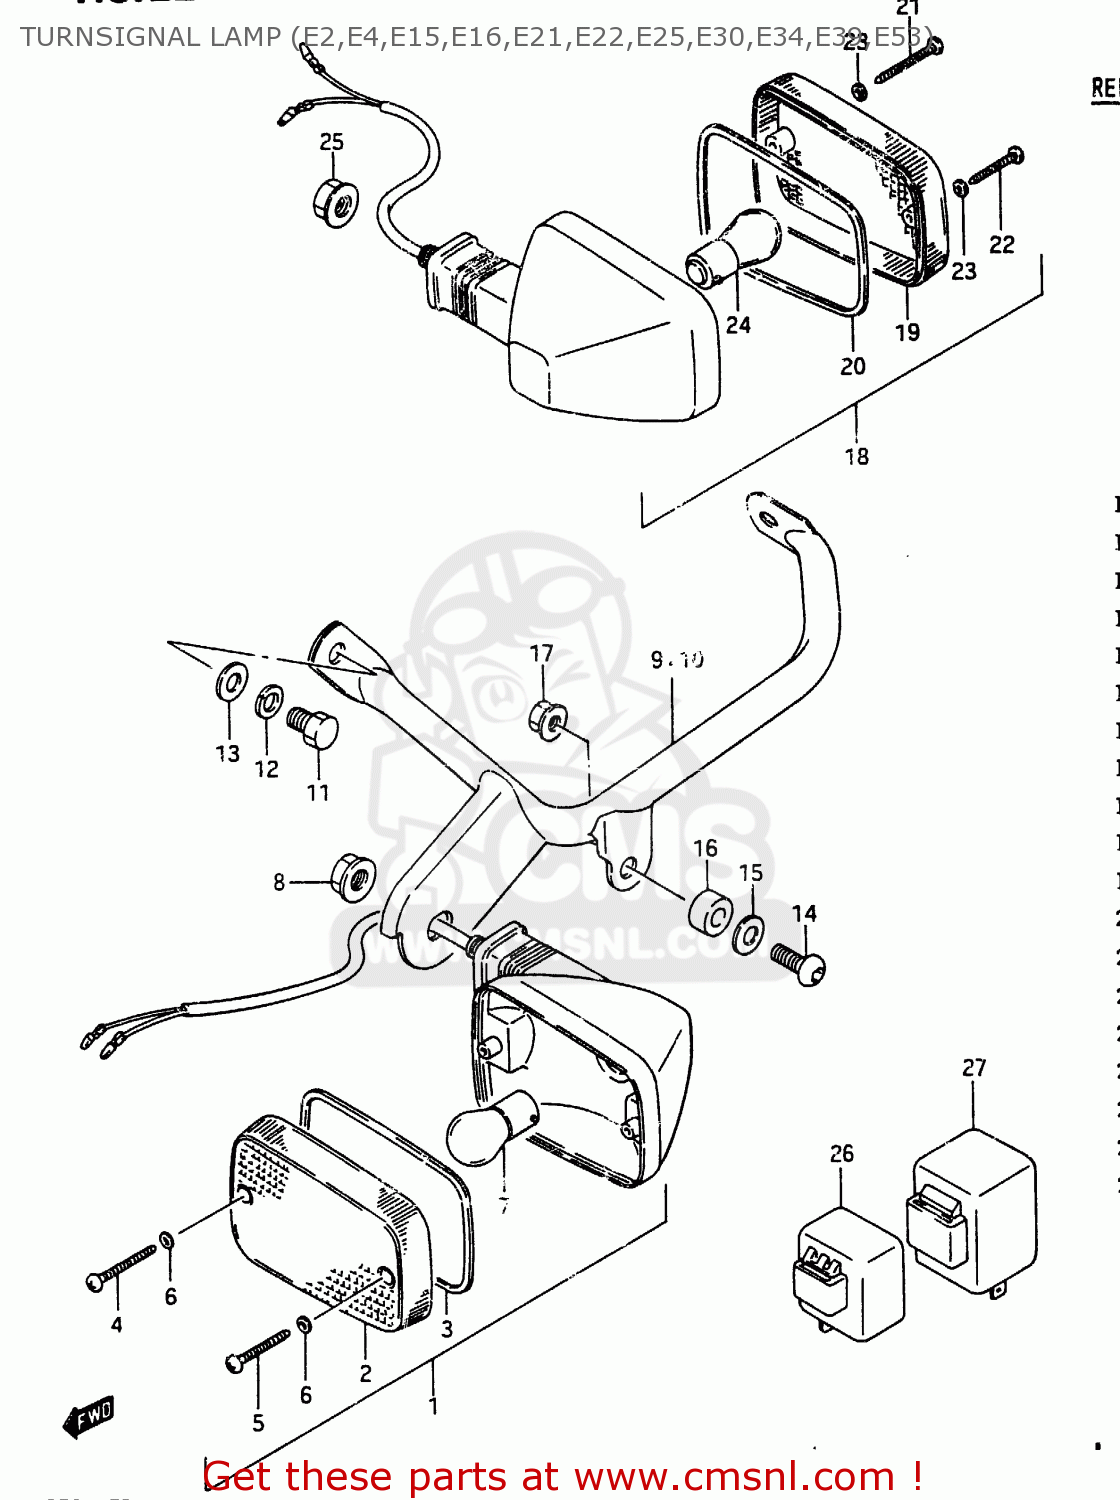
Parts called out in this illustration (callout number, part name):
1	LAMP ASSY,FR
2	LENS,FR
3	GASKET (NAS)
4	SCREW,TURN SIG LENS FITTING
5	SCREW
6	GASKET (NAS)
7	BULB(12V21W)
8	NUT
9	BRACKET, FRONT TURNSIGNAL RH
10	BRACKET,FR TURNSIGNAL,L
11	BOLT
12	WASHER,LOCK,8.
13	WASHER
14	SCREW(6X30)
15	WASHER(6.5X16X1.2)
16	SPACER(6.1X8X14.5)
17	NUT
18	LAMP ASSY,RR
19	LENS,RR
20	GASKET (NAS)
21	SCREW,TURN SIG LENS FITTING
22	SCREW
23	GASKET (NAS)
24	BULB(12V21W)
25	NUT
26	RELAY ASSEMBLY,TURN SIGNAL
27	RELAY ASSY,TUR
